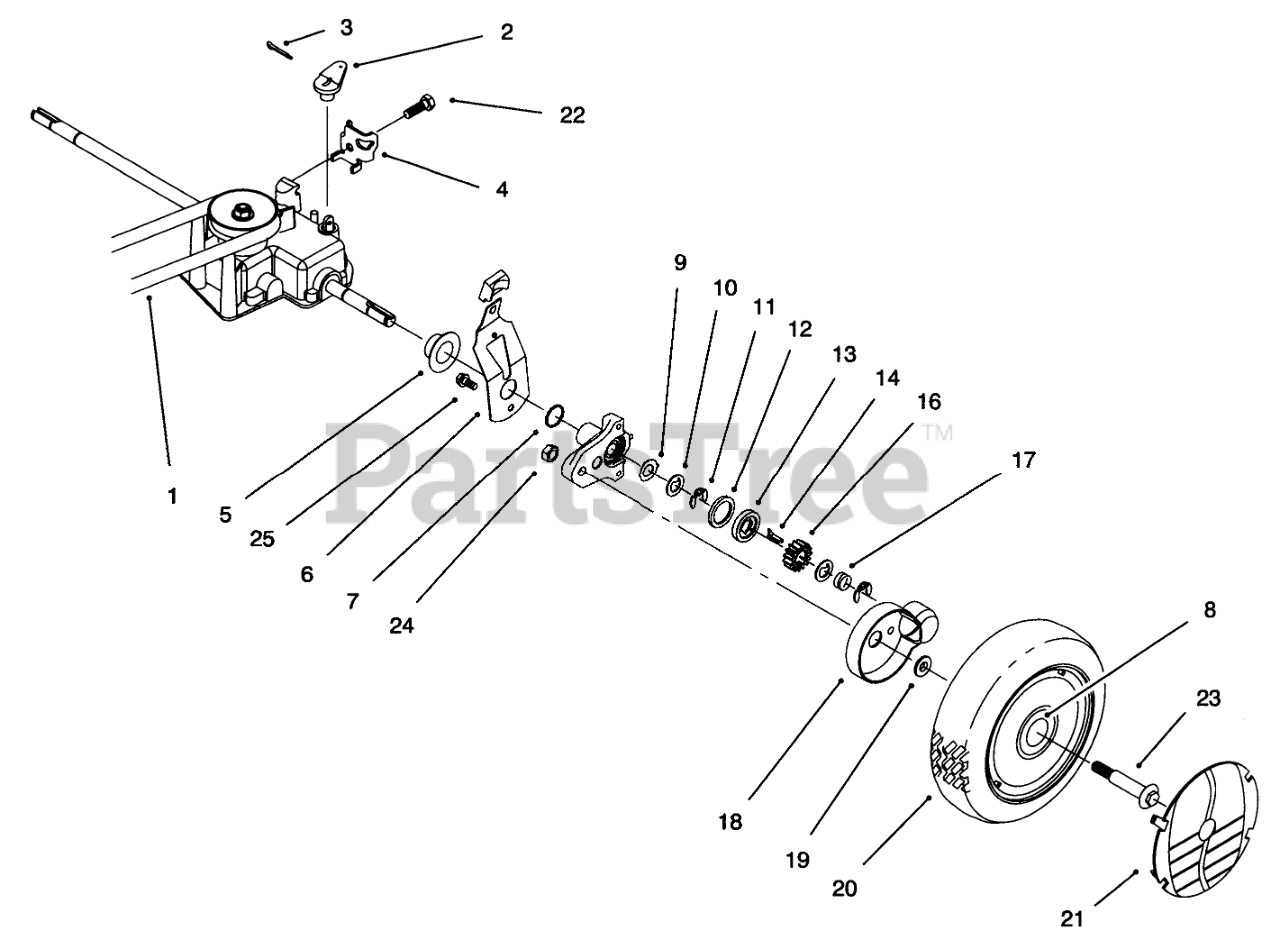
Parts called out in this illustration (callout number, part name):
1	V-BELT E
2	LEVER-SHIFT
3	PIN-COTTER
4	CLAMP-CABLE
5	CAP-END
6	SPRING ARM ASM
7	O-RING
8	BUSHING
9	WASHER-ARM, PIVOT
10	WASHER-THRUST, KEYED
11	RING-CLIP, LOCKING
12	RING-FRICTION
13	WASHER-CLUTCH
14	KEY-ROCKING, LH
16	GEAR-PINION
17	SPRING-COMPRESSION
18	COVER-WHEEL
19	SPACER-COVER, WHEEL
20	Wheel & Tire Assembly (Incl. Ref. #8)
21	WHEEL COVER
22	SCREW-HWHTF
23	BOLT-WHEEL
24	NUT-LOCK
25	SCREW-HWH
